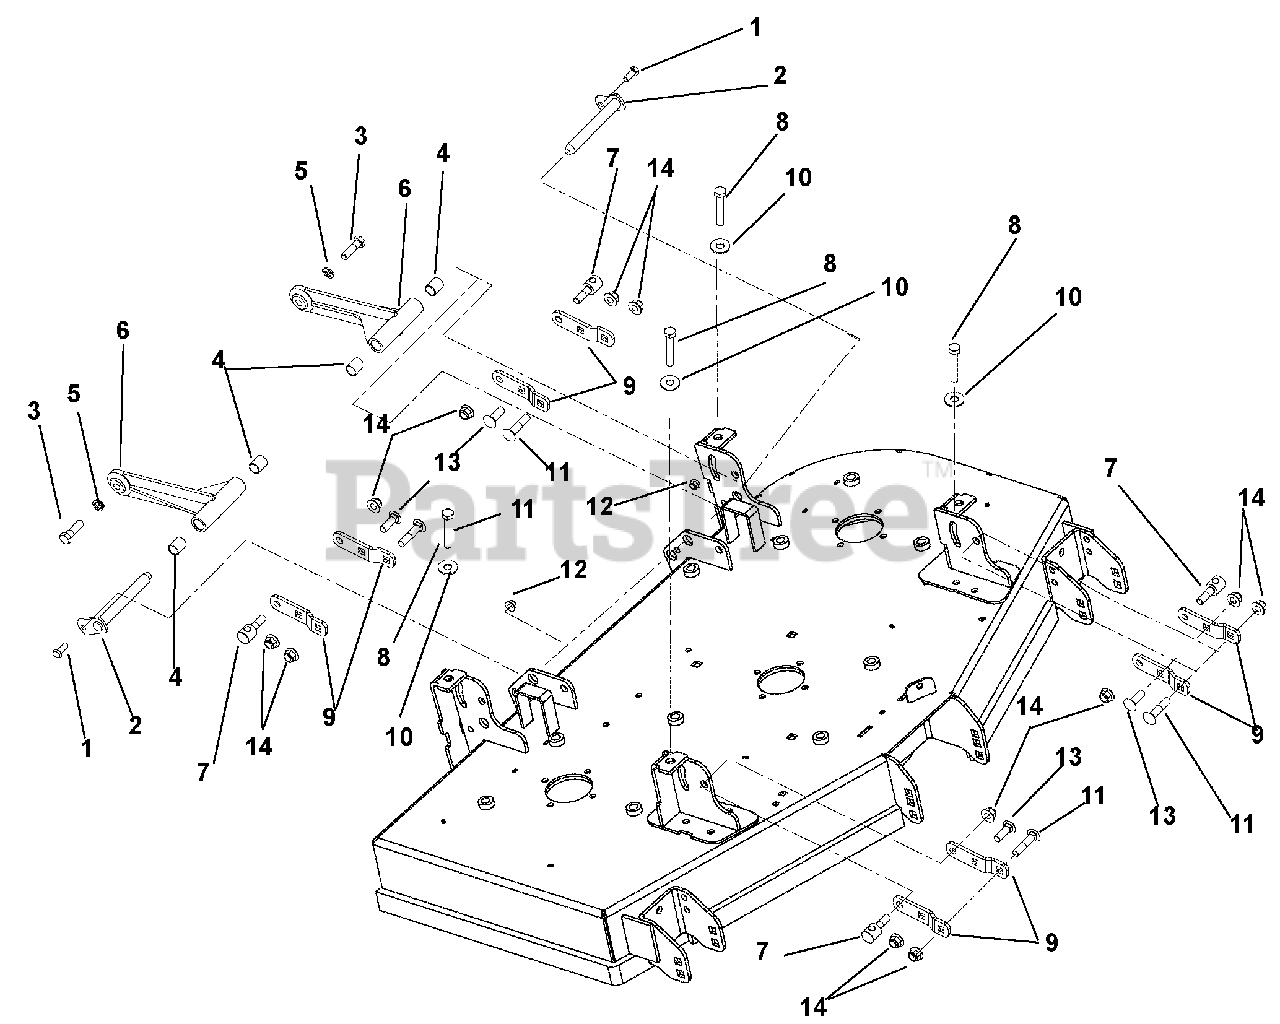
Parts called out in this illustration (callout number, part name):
1	Bolt, Hex .38-16 x 1.00
2	Weldment, Mower Mounting Pin
3	Bolt, Hex .50-13 x 1.75 Grade 5 EP80
4	Bearing, .75 x .875 x 1.00
5	Washer, Locking .50 x .125 Regular
6	Deck Pusher Arm Weldment, Black
7	Trunnion, .50-13
8	Bolt, Hex .50-13 x 3.00
9	Bracket, Deck Leveling
10	Washer, Flat Steel .563 x 1.38 x .109
11	Bolt, Round Head Square Neck .50-13 x 2.25
12	Nut, Locking Nyloc Flange .38-16
13	Bolt, Round Head Square Neck .50-13 x 1.50
14	Nut, Locking Nyloc Flange .50-13
